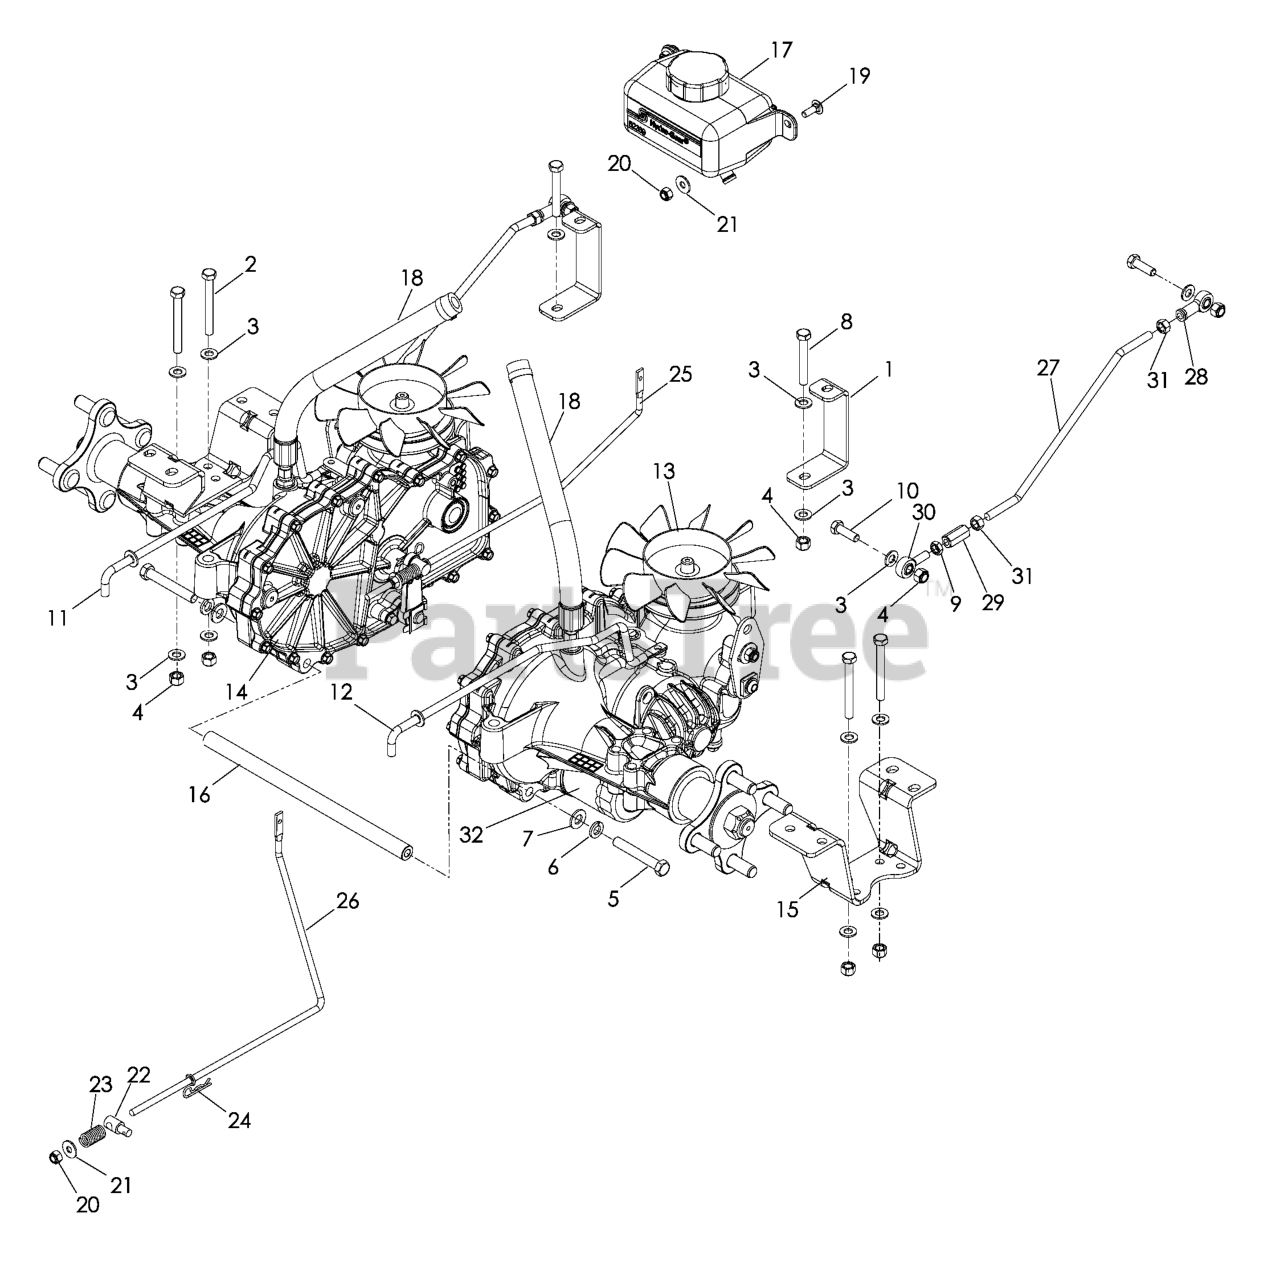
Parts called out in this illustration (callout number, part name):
1	SUPPORT.FRONT.TRANS.BLACK.
2	HCS 5/16C X 2-3/4
3	FLAT WASHER 5/16 SAE
4	NUT 5/16 NYLOC
5	HCS 3/8C X 2 1/2
6	SLW 3/8 STD
7	WASHER 3/8 SAE FLAT
9	NUT 5/16F LEFTHAND
10	HCS 5/16C X 1
11	ROD, BYPASS, RT
12	ROD, BYPASS, LT
13	HG_TRANS, ZT-2800 RT
14	HG_TRANS, ZT-2800 LEFT
15	EZT MOUNT, REAR, BLACK
16	SPACER TUBE, EZT, 11.08
17	HG_EXPANSION TANK W/CAP 71354
19	RHSNB 1/4C X 3/4
20	NUT.1/4-20.HEX.NYLOC.ZD
21	WASHER 1/4 FLAT
22	BRAKE SWIVEL
24	HAIRPIN #2
25	ROD EZT BRAKE LT
26	ROD EZT BRAKE RT
27	ROD, MOTION CONTROL
28	RH ROD END
29	ROD END COUPLER
30	RP.ROD.END.LH
32	HG_FILTER, ZT4800 52114
